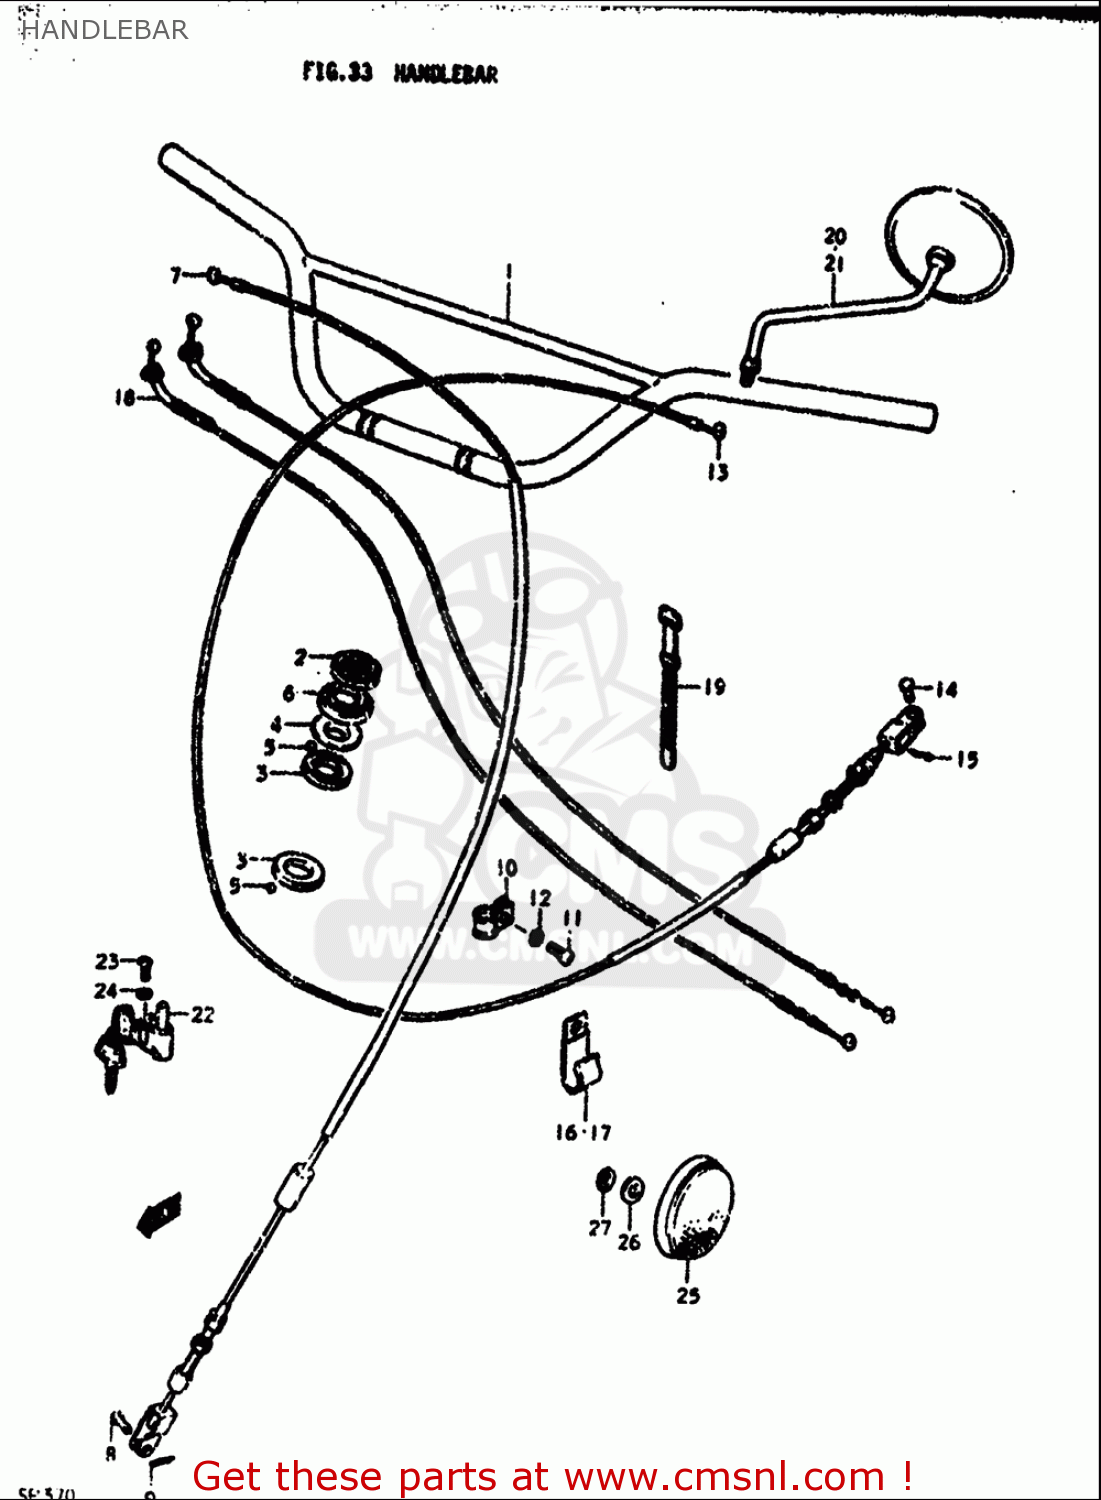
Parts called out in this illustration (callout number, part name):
1	HANDLEBAR
2	NUT,STEERING STEM(25X44X10)
3	LACE,STEERING INNER LWR
4	LACE,STEERING OUTER UPR
5	BALL
6	DUST SEAL,STEERING UPR
7	CABLE ASSY,FR BRAKE
8	PIN(L:17.5)
9	PIN
10	GUIDE,CABLE
11	SCREW
12	WASHER,LOCK
13	CABLE,CLUTCH
14	PIN(L:15)
15	PIN
16	CLAMP(L:120 T:1.0)
17	CLAMP
18	CABLE ASSY,THROTTLE
19	CLAMP(L:120)
20	MIRROR ASSEMBLY,RIGHT
21	MIRROR ASSEMBLY,LEFT
22	LOCK ASSY,STEERING
23	SCREW
24	WASHER,LOCK
25	REFLEX REFLECTOR,FR
26	WASHER
27	WASHER,LOCK
